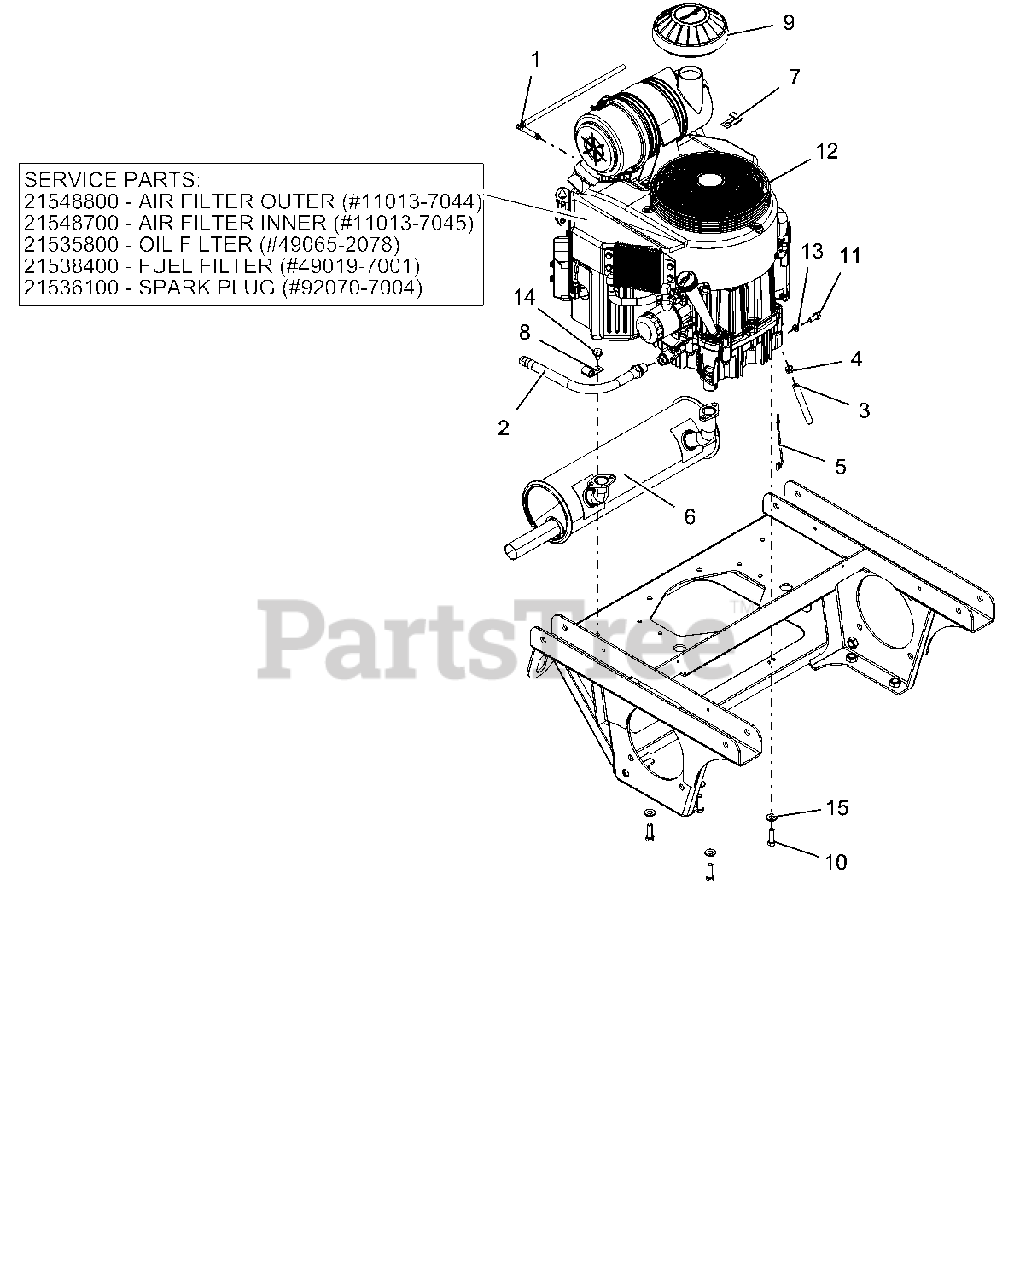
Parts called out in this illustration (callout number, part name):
1	ASM, KAWASAKI VAPOR LINE
2	HOSE, OIL DRAIN
3	.25 LOW-PERM GAS HOSE 16.00" LG - VALVE TO ENGINE
4	CLAMP, FUEL LINE
5	LEAD - STARTER SOLENOID
6	MUFFLER, 27-31 FX KAW
7	CLAMP, J
9	CAP, AIR CLEANER INTAKE (2")
10	BLT-HEX .38-16X1.25 GR5 YWZC NYTORQ
11	@BLT-HEX M8-1.25X20 YWZC
12	ENGINE, KAWASAKI FX850
12	AIR FILTER OUTER, #11013-7044
12	AIR FILTER INNER, #11013-7045
12	OIL FILTER, #49065-2078
12	FUEL FILTER, #49019-7001
12	SPARK PLUG, #92070-7004
13	WSHR-LK .31X.078 REG YWZC
14	SCR-TAP .38-16X.50 HWH TR YWZ
15	WSHR, 3/8" SPRING DISC
